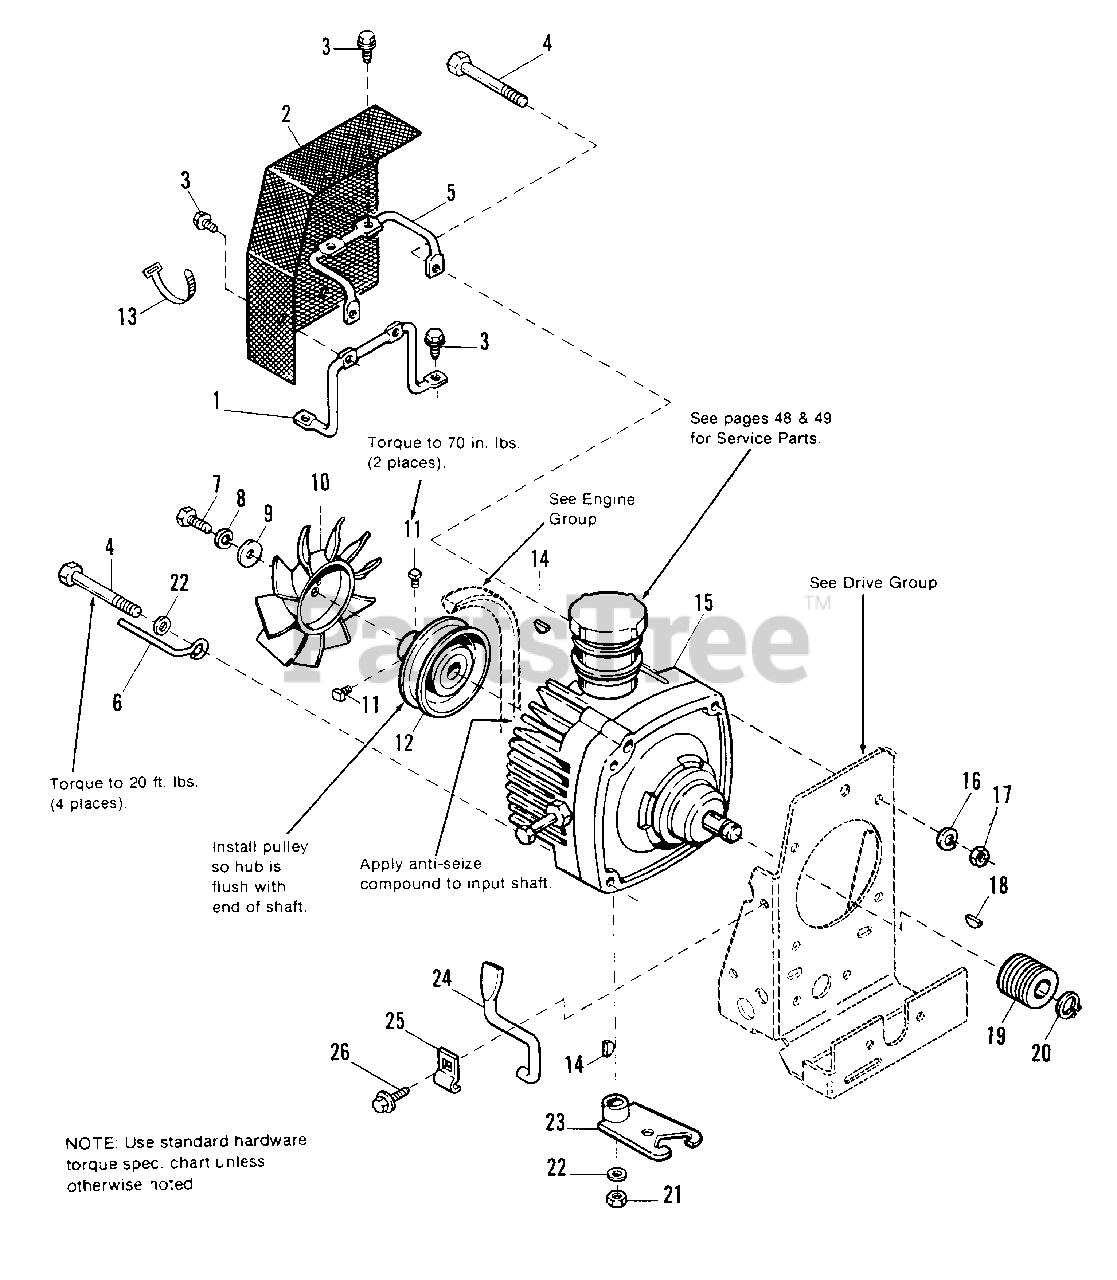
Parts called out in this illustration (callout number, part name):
1	MOUNTING BRACKET, Fan Guard
3	SCREW, Hex Taptite, 1/4-20 x 1/2
4	CAPSCREW, Hex 3/8-16 x 3
5	MOUNTING BRACKET, Fan Guard
7	CAPSCREW, Hex, 1/4-20 x 1/2
8	LOCKWASHER, 1/4
9	WASHER, 1/4 x 1-1/4
11	SETSCREW, Sq. Hd., Cup Pt., 1/4-28 x 1/2
12	PULLEY, Transmission
14	KEY, Woodruff
15	TRANSMISSION-Hydro(See pages 48 & 49 for Service Parts)
16	LOCKWASHER, 3/8
17	NUT, Hex, 3/8-16
18	KEY, Woodruff
19	PULLEY, Drive
20	RING, Retaining
21	NUT, Hex Lock, 5/16-18
22	WASHER, 5/16
23	CONTROL ARM ASSY.
24	ROD, Tow Latch
25	CLIP, Tow Latch
26	SCREW, Taptite, 5/16-18 x 1/2
